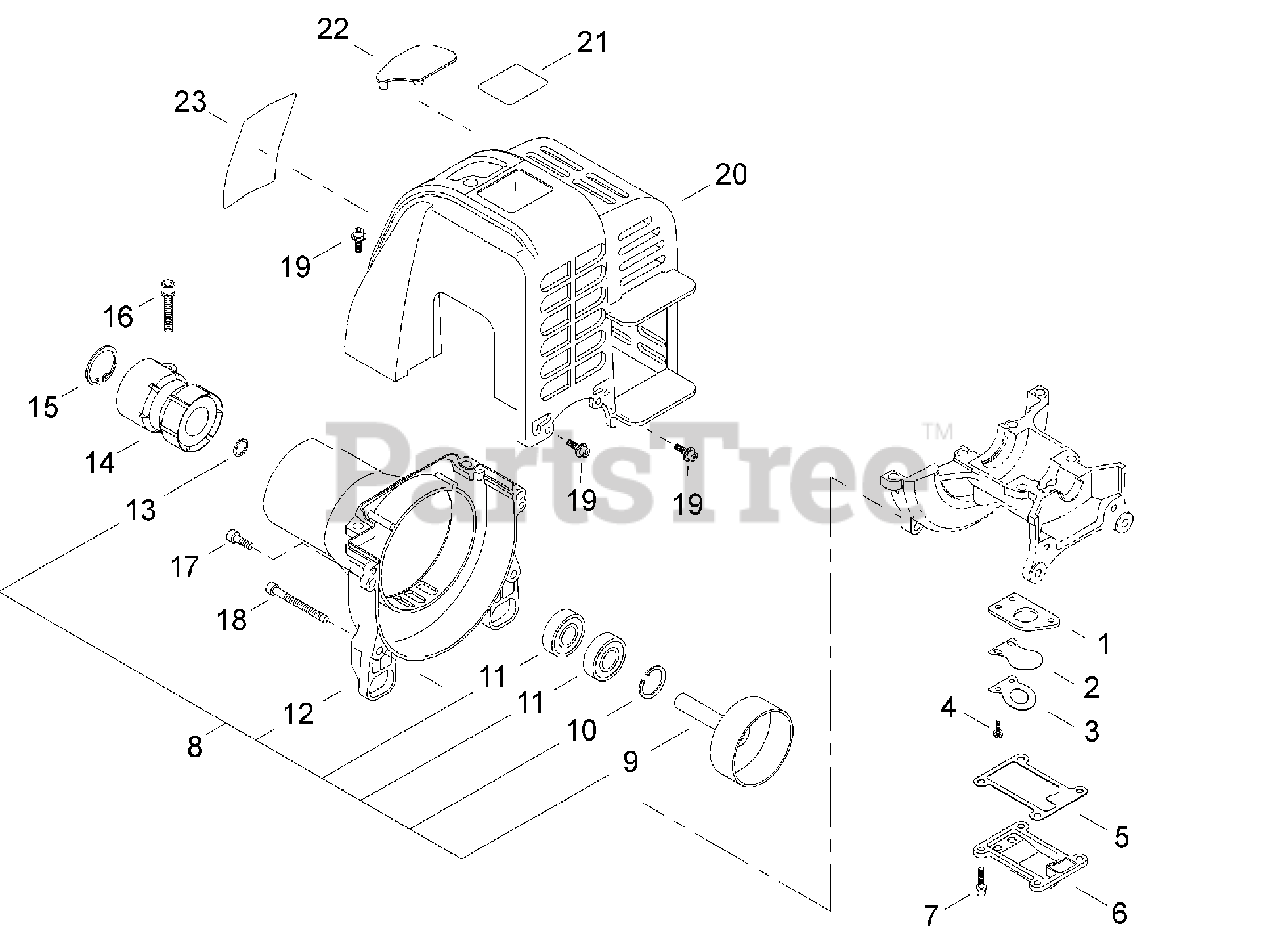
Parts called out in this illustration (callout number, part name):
1	PLATE, REED BACKING
2	VALVE, REED
3	STOP, REED VALVE
4	SCREW - 3X10
5	GASKET, REED VALVE
6	COVER, REED VALVE
7	SCREW - 4X12
8	FAN CASE ASSY
9	DRUM, CLUTCH
10	RING, RETAINING - 26
11	BEARING, BALL - 6000
12	CASE, FAN
13	RING, RETAINING
14	CUSHION
15	RING, RETAINING - 40
16	SCREW - 5X22
17	SCREW - 5X16
18	SCREW - 5X45
19	SCREW - 4X16
20	COVER, ENGINE
21	LABEL - MODEL E3000
22	COVER, SPARK PLUG
23	LABEL - E4
